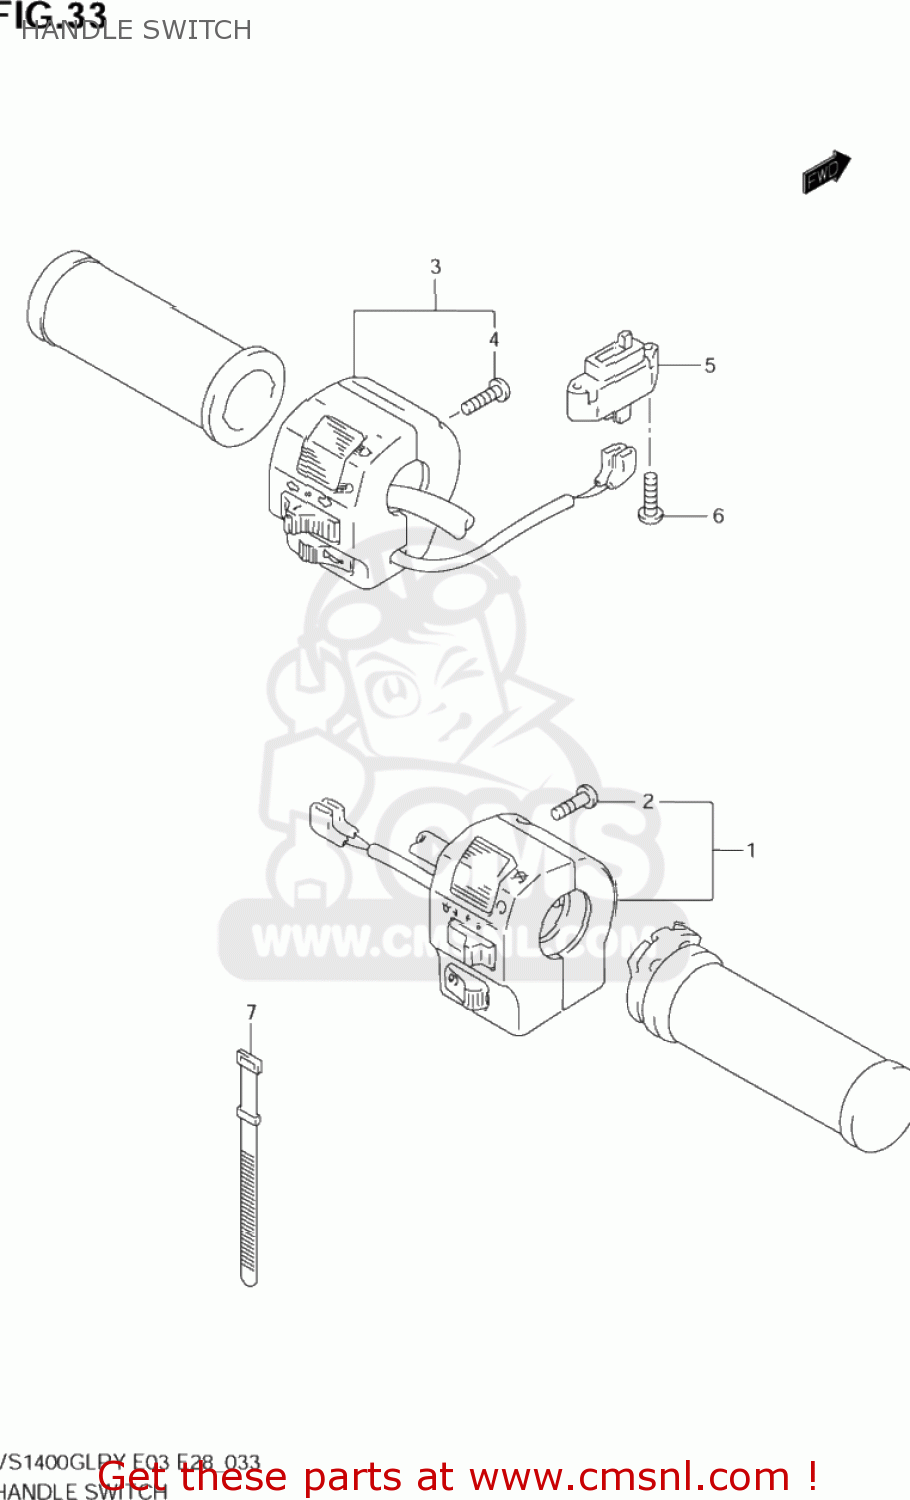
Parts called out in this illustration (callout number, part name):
1	SWITCH ASSY,HANDLE,R
2	SCREW
3	SWITCH ASSY,HANDLE,L
4	SCREW
5	SWITCH ASSY,CLUTCH
6	SCREW
7	CLAMP
